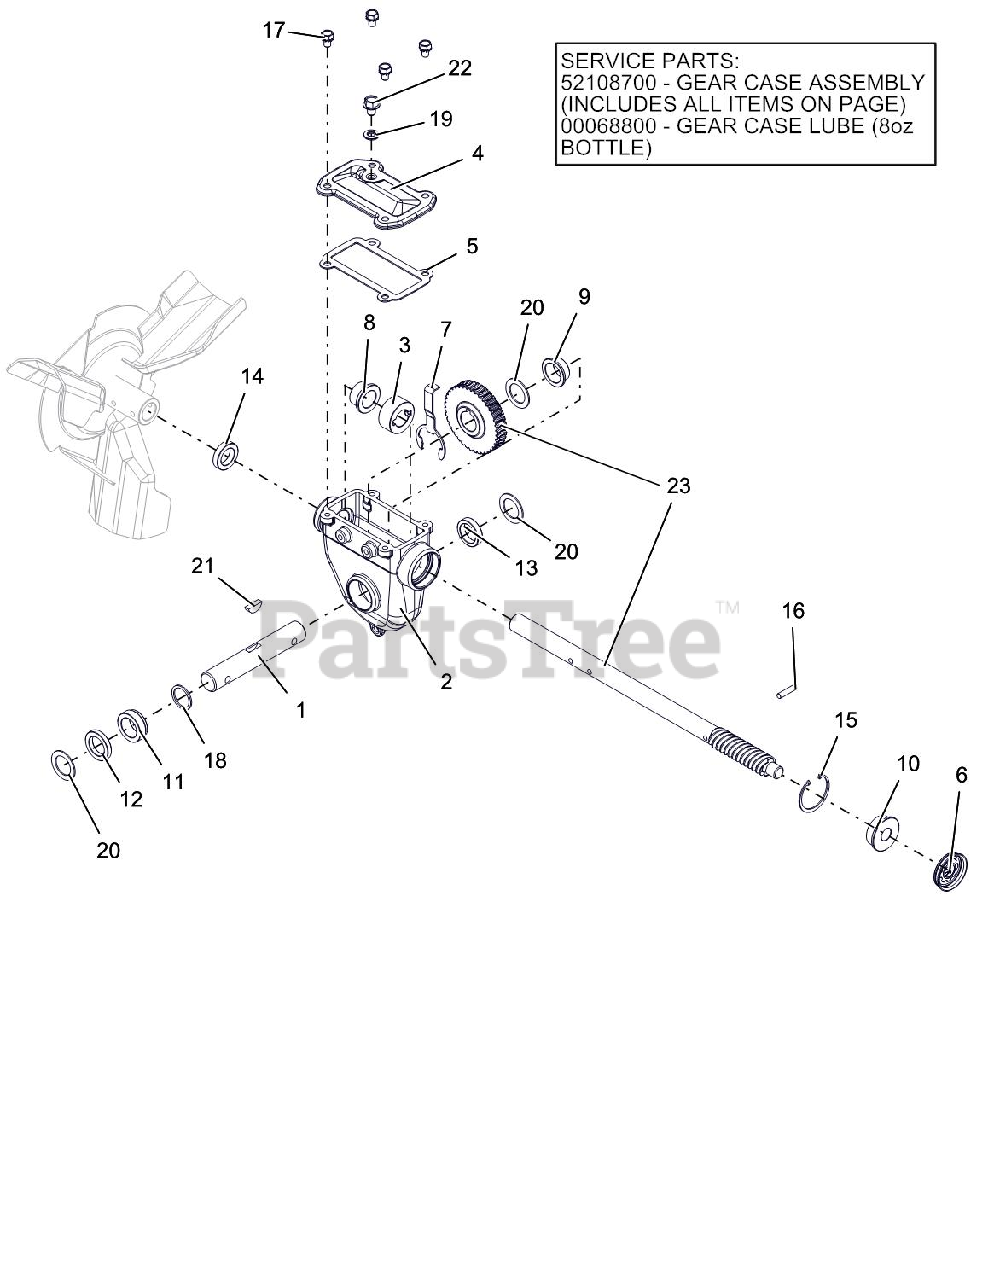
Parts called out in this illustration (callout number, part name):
1	RAKE SHAFT, SHORT-COMMON
2	GEARCASE, LARGE MACHINED
3	THRUST COLLAR, .875"ID SLIPFIT
4	COVER, TOP - LARGE IRON
5	GASKET, TOP - LARGE GEARCASE
6	COVER, GEAR CASE 1.75"
7	BUSHING RETAINER, LARGE
8	BSHG-FLG .879X1.128X.75X1.45
9	BSHG-FLG 1.006X1.128X.555X1.45
10	BSHG-FLG .628X1.503X.58X1.725
11	BSHG-FLG LARGE, RIGHT
12	SEAL-OIL .999X1.500X.250 TBC29
13	SEAL-OIL .999X1.375X.312 TBC29
14	SEAL-OIL .873X1.375X.312 TBC29
15	RG-RTNG-INT 1.750X.062
16	PIN-STR .250X1.12 6150
17	BOLT, SEMS .31-18X.50 GR5 YWZC
18	WSHR-FL-STL 1.010X1.250X.068YZ
19	WSHR-BND-SEAL .38X.75X.11 GALV
20	WSHR-FL-STL 1.010X1.505X.062YZ
21	KEY-WDRF .25X.875 HRD #A
22	@SCR-ROLOK .38-16X.50 HWH YWZC
23	KIT, SERVICE-WORM SHAFT & GEAR
24	KIT, SERVICE - DLX GEAR CASE
25	ARIENS L3 LUBE, 8 OZ BOTTLE
